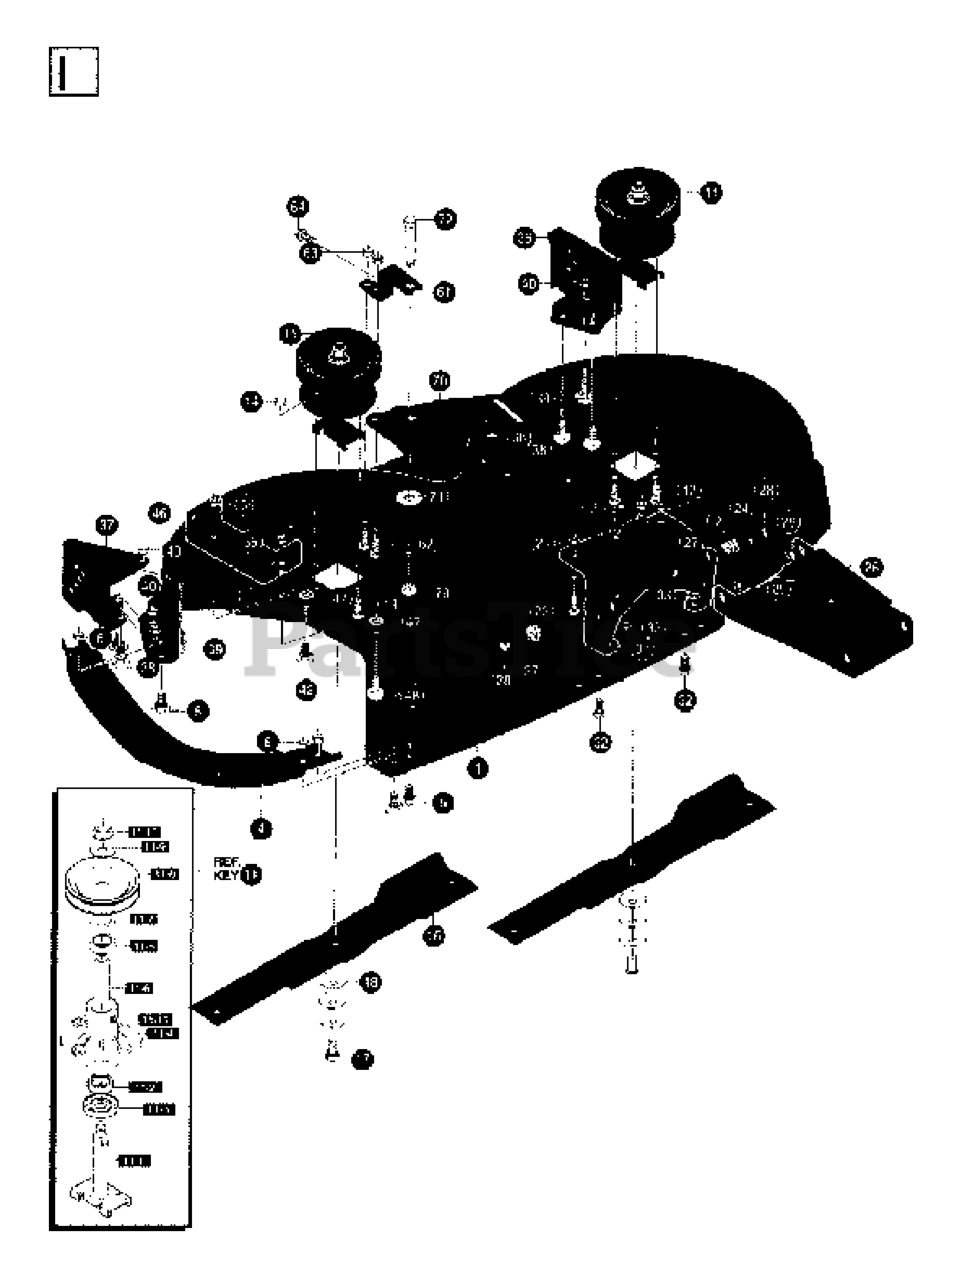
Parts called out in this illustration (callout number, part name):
1	DECK ASSY
2	SCREW
3	NUT
5	BOLT.CARR.SQNK.5/16-18UNC.X3/4
6	NUT
12	SCREW
13	SCREW
14	NUT
17	SCREW 3/8 - 16X1
23	BOLT.CARR.SQNK.5/16-18UNC.X3/4
24	NUT
26	CHANNEL DRAWBAR
28	SCREW
29	NUT
31	BRACKET, FRONT
32	SCREW
33	NUT
36	HOLDER, L.H.
37	HOLDER, R.H.
38	SCREW
39	BOLT.CARR.SQNK.5/16-18UNC.X3/4
40	NUT
47	WASHER - M6
48	BOLT.CARR.SQNK.5/16-18UNC.X3/4
55	NUT
62	SCREW
63	NUT
74	WASHER - M12
78	NUT.HEX.3/8-16UNC
